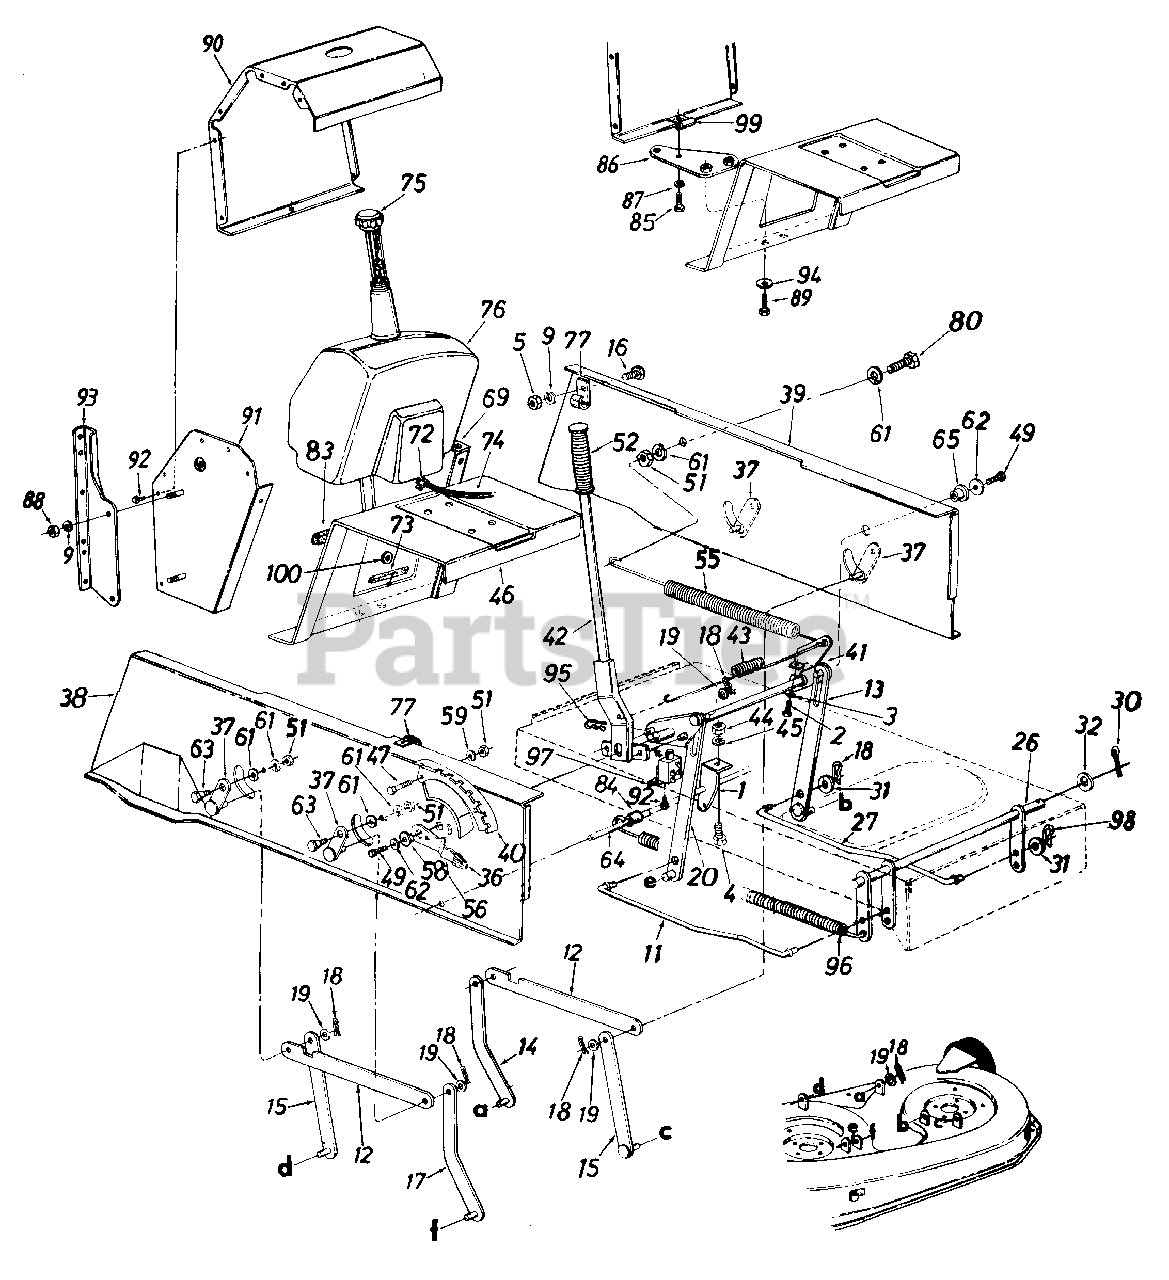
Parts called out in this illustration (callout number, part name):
1	Spring Hanger Bracket
2	Hex Tap. Scr. 5/16-18 x 1
3	Hex Jam Nut 5/16-18 Thd.
4	Hex Bolt 1/4-20 x .62" Lg.*
5	Hex Nut 5/16-18 Thd.
9	L-Wash. 5/16" I.D.*
11	Stabilizer Rod
12	Connecting Rod
16	Hex Bolt 5/16-18 x .75" Lg.
17	Deck Hanger Link Ass'y.-
18	Inter. Cotter Pin 1/2" Dia.
19	Fl-Wash. .531" I.D. x .93" O.D.
20	Deck Lift Link Ass'y.
26	Stabilizer Shaft Ass'y.
27	Stabilizer Rod
30	Cotter Pin 1/8" Dia. x 1.25"
31	Fl-Wash. .385" I.D. x .620" O.D.
32	Fl-Wash. .635" I.D. x 1.12" O.D.
36	Knob-Height Adj.
37	Pivot Link Ass'y.
38	Side Panel Upper Frame-R.H.
39	Side Panel Upper Frame-L.H.
40	Index Brkt.
41	Lift Shaft Ass'y.
42	Lift Handle Brkt. Ass'y.
43	Ext. Spring
44	Hex Nut 1/4-20 Thd.
45	L-Wash. 1/4" I.D.
46	Hitch Plate
47	Hex Bolt 5/16-18 x .75" Lg.
49	Hex Wash. TT-Tap Scr. 5/16-18 x .62" Lg.
51	Hex Nut 5/16-18 Thd.
52	Grip
55	Ext. Spring 11" Lg.
56	Deck Lift-Down Stop
58	Flange Brg. .630" I.D.
61	Bell-Wash. .325" I.D. x .930" x.045"
62	Fl-Wash. .344" I.D. x 1.125" O.D.
63	Shld. Bolt .437" Dia. x .180"
64	Running Board Rod
65	Flange Brg. .632" I.D.
73	Trim Strip-5" Lg.
74	Gas Line-68" Lg.
75	Gas Tank Cap
76	Gas Tank
77	Hose Clamp
80	Hex Bolt 5/16-18 x 1.50" Lg.
83	Foam Strip 3/8" x 1-1/8" x 1-1/2" Lg.
84	Spacer .523" I.D. x .640" O.D. x 1.95" Lg.
85	Hex Bolt 5/16-18 x 1" Lg. Gr. 5
86	Hitch Bar
87	L-Wash. 5/16" I.D.
88	Hex Nut 5/16-18 Thd.
89	Self-Tap Scr. 3/4" Lg.
90	Gas Tank Housing
91	Side Panel-R.H.
92	Truss Mach. B-Tap Scr. #10 x .50" Lg.
93	Mounting Bracket-R.H.
94	Bell-Wash. 3/8" I.D.
95	Internal Cotter Pin 3/8" Dia.
96	Ext. Spring 13.25" Lg.
97	Safety Switch
98	Cotter Pin 3/32" Dia.
99	Speed Nut
100	Grommet
